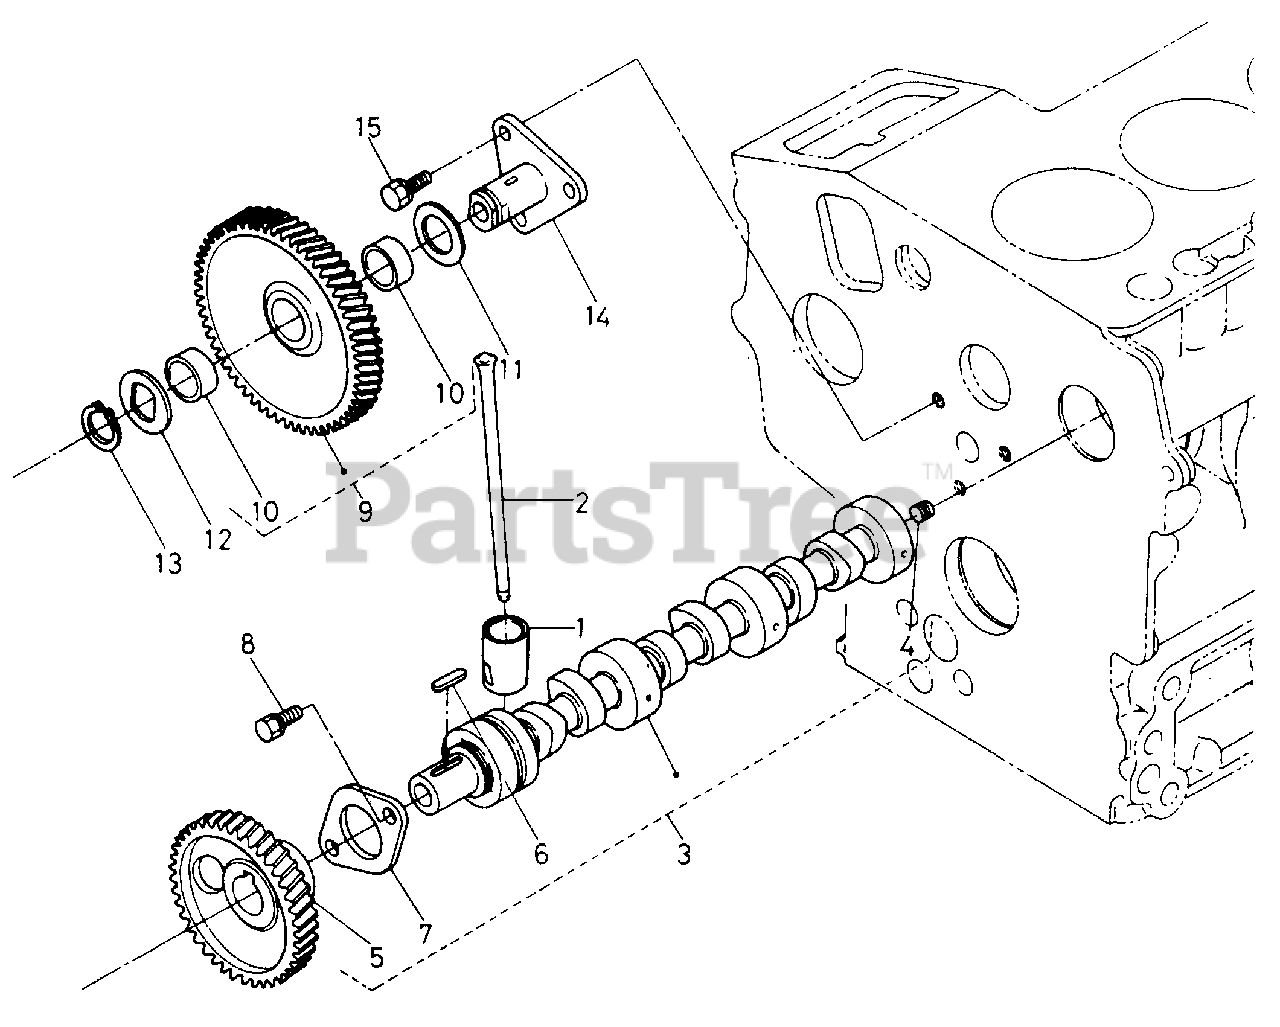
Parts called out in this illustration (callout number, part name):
3	Camshaft w/Gear
5	Gear, Camshaft
7	Stop, Camshaft
8	Bolt, M6 X 12 Class 8.8
9	Gear Assy, Idler
11	Collar, Idler Gear
12	Collar, Idler Gear
13	Ring, Retaining
14	Shaft, Idler Gear
15	Bolt, M6 X 14MM Class 8.8
